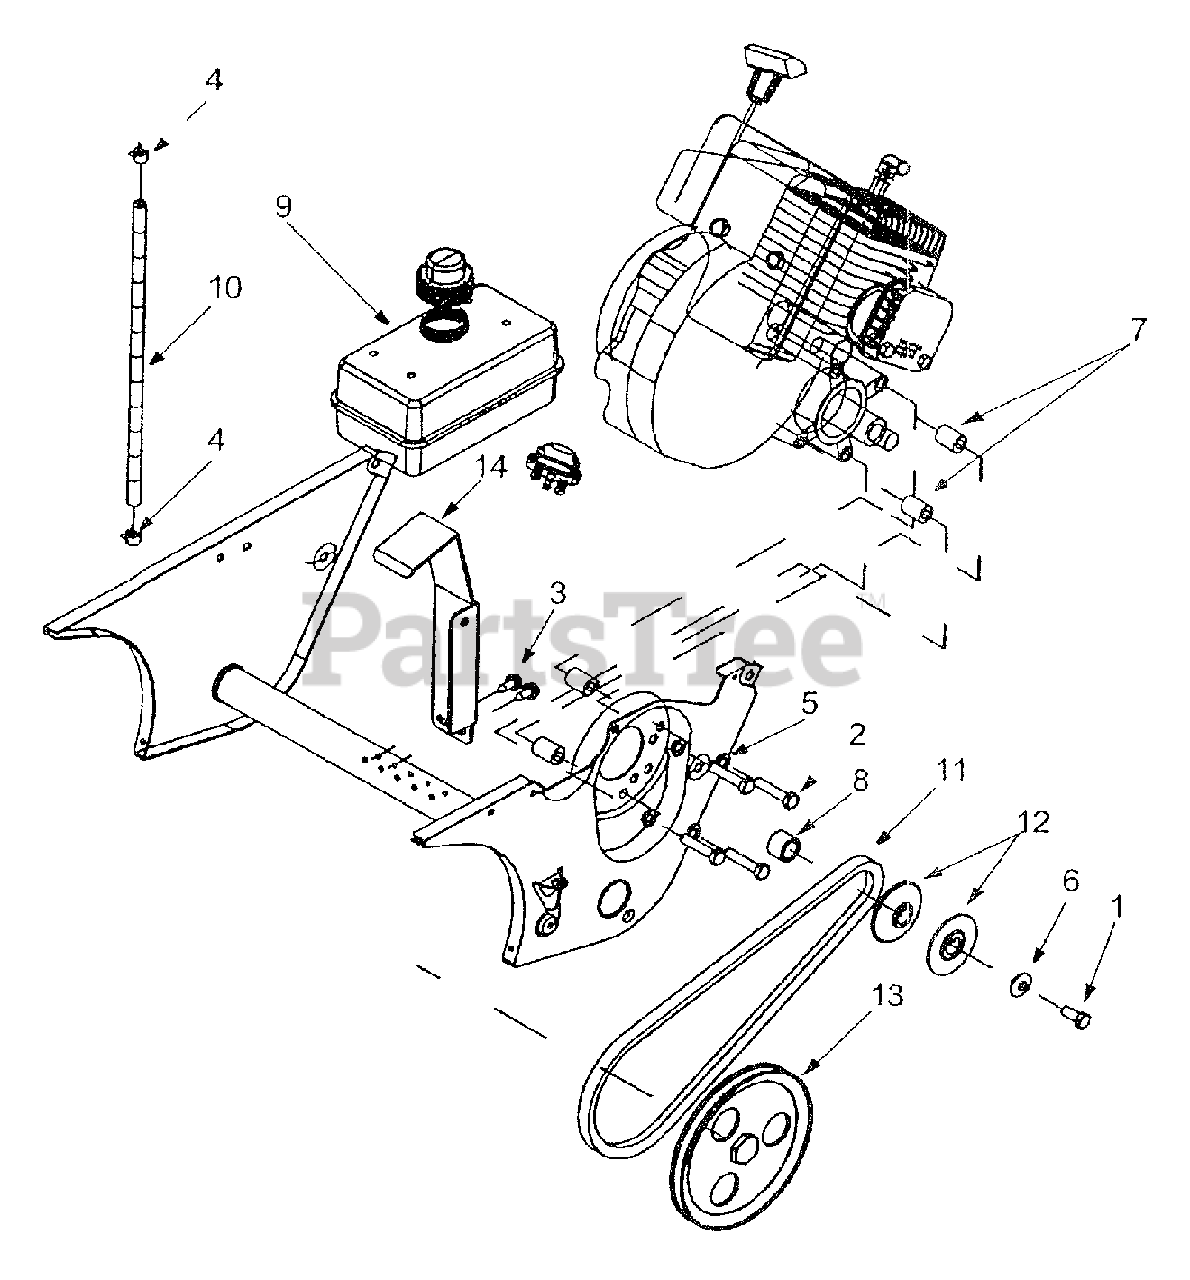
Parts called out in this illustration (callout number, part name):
1	Hex Screw 5/16-24 x 0 75"
2	Hex Screw 5/16-18 x 1 5"
3	Self-Tapping Screw 1/4-20 x 625"
5	Lock Washer
6	Beleville Washer
7	Spacer
8	Spacer
9	Gas Tank : 1 quart
10	Fuel Line Hose
11	V-Belt
12	V-Pulley Half
